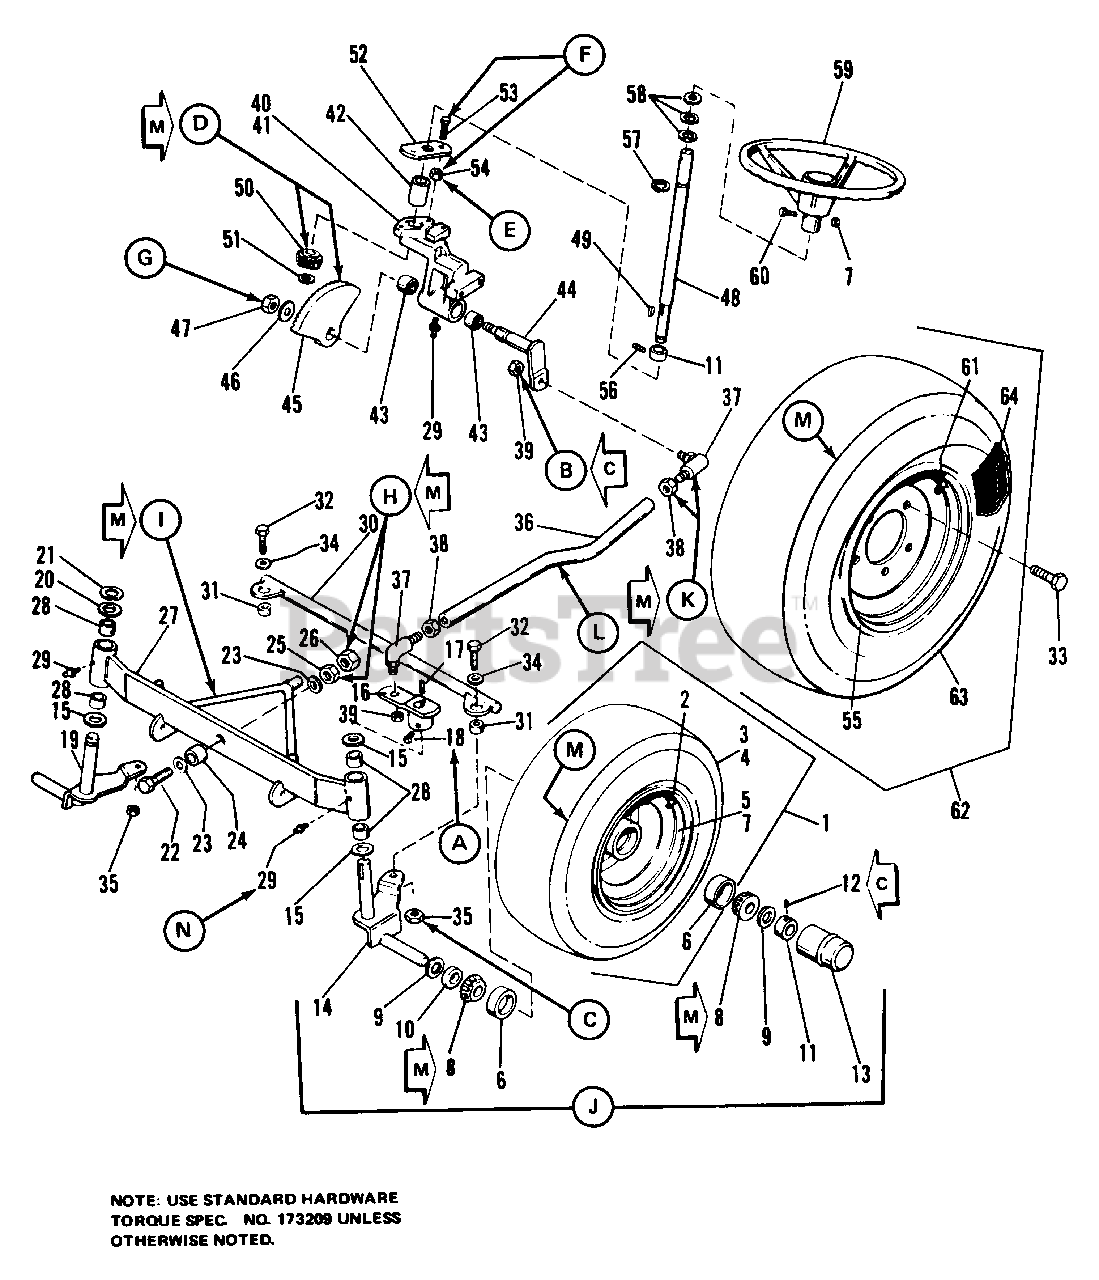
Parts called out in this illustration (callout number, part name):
1	WHEEL & TIRE ASSEMBLY
2	VALVE STEM & CAP
3	TIRE, 16-6.50 x 8 Goodyear
3	TIRE, 16-6.50 x 8, Carlisle
4	TUBE, 16-6.50 x 8
5	WHEEL ASSEMBLY
6	CUP, Bearing
7	LOCKNUT, flange, 5/16-18
8	CONE, Bearing
11	COLLAR, Set
12	SETSCREW, Sq. Hd., Cup Pt., 5/16-18 x 5/16
13	CAP, Hub
14	SPINDLE ASSY, L.H.
16	ARM, Steering, L.H.
17	KEY, Square
18	SETSCREW, 5/16-18 x 1/2
19	SPINDLE ASSY, R.H.
21	RING, Retaining, No. 75
22	CAPSCREW, Hex Hd., 1/2-13 x 2-1/4
23	WASHER, Plain, 1/2
25	LOCKNUT, Hex, 1/2-13
26	NUT, Jam Hex, 1/2-13
27	FRONT AXLE ASSY (with bushings)
29	FITTING, Grease
30	TIE ROD ASSY
32	CAPSCREW, Hex Hd., 3/8-16 x 1-1/4
34	WASHER, Plain, 3/8
35	LOCKNUT, Hex, 3/8-16
36	LINK, Drag
37	JOINT, Ball
38	NUT, Jam Hex, 1/2-20
39	LOCKNUT, Hex, 1/2-20
40	STEERING HOUSING ASSEMBLY (Incl. 42 & 43)
41	HOUSING, Steering
42	BUSHING, Steering
43	BEARING, Needle
44	STEERING ARM ASSEMBLY
45	GEAR, Bevel
46	WASHER, Plain, 7/16
47	LOCKNUT, Hex, 7/16-14
48	SHAFT, Steering
49	KEY, Woodruff, No. 6, 5/32 x 5/8
50	PINION, Bevel
51	"E" RING
52	PLATE, Steering
53	CAPSCREW, Hex Hd., 3/8-16 x 1-1/4
54	LOCKNUT, 3/8-16
55	WHEEL DRIVE
56	SETSCREW, Sq. Hd., 5/16-18 x 1/4
57	RING, Retaining
59	WHEEL, Steering
60	CAPSCREW, Hex Hd., 5/16-18 x 1-1/4
61	STEM & VALVE CAP
62	WHEEL & TIRE ASSEMBLY, 23-10.50 x 12
63	TIRE, 23-8.50 x 12 Goodyear
63	TIRE, 23-8.50 x 12, Carlisle
64	TUBE, 23-8.50 x 12
